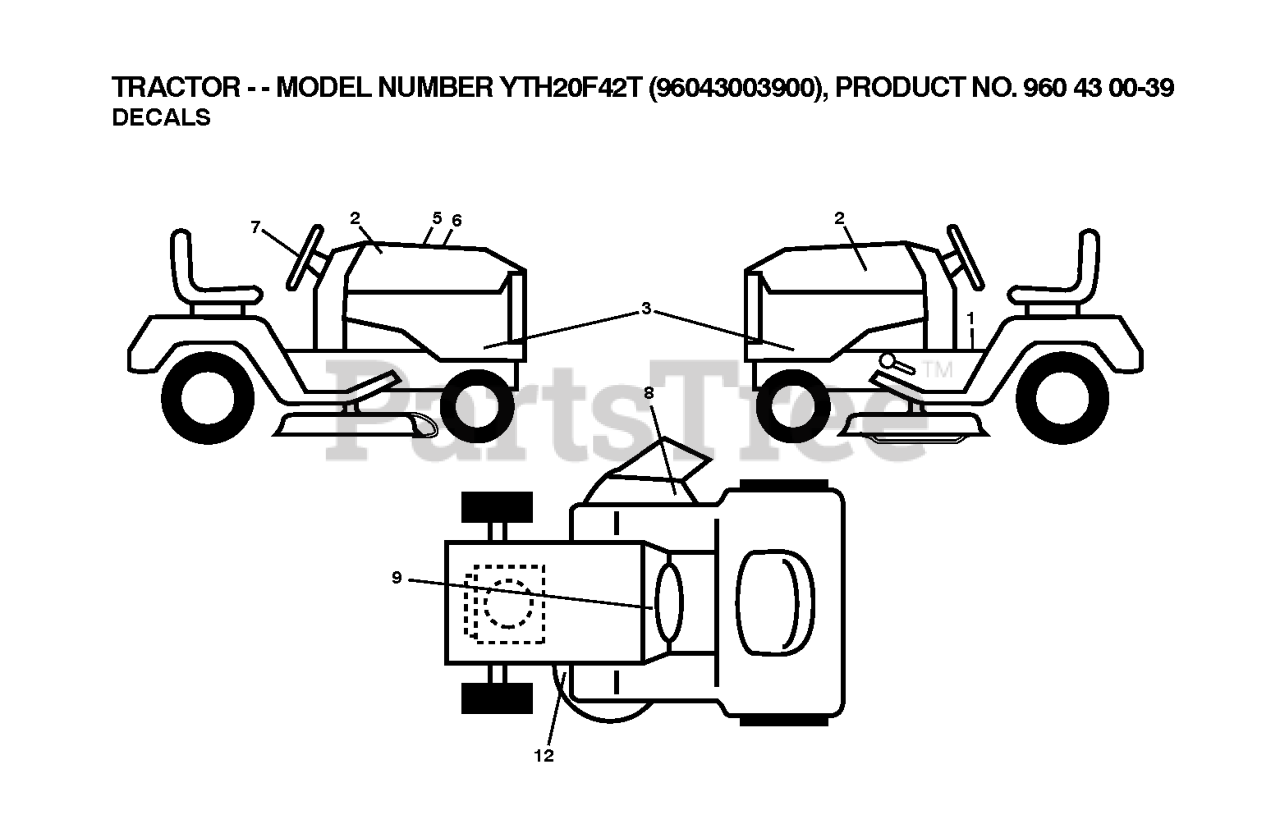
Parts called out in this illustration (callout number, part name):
1	DECAL.FENDER.WARNING.ENG
2	DECAL.HOOD.LOGO.HUSQVARNA
5	DECAL HOOD CUST. RESP.
7	DECAL.WHEEL.STRG.LGN.H
8	DECAL.WARN.KEEP.HAND.AWAY
9	DECAL BTRY SYMBOLS
12	DECAL V BELT SCHEMATIC
